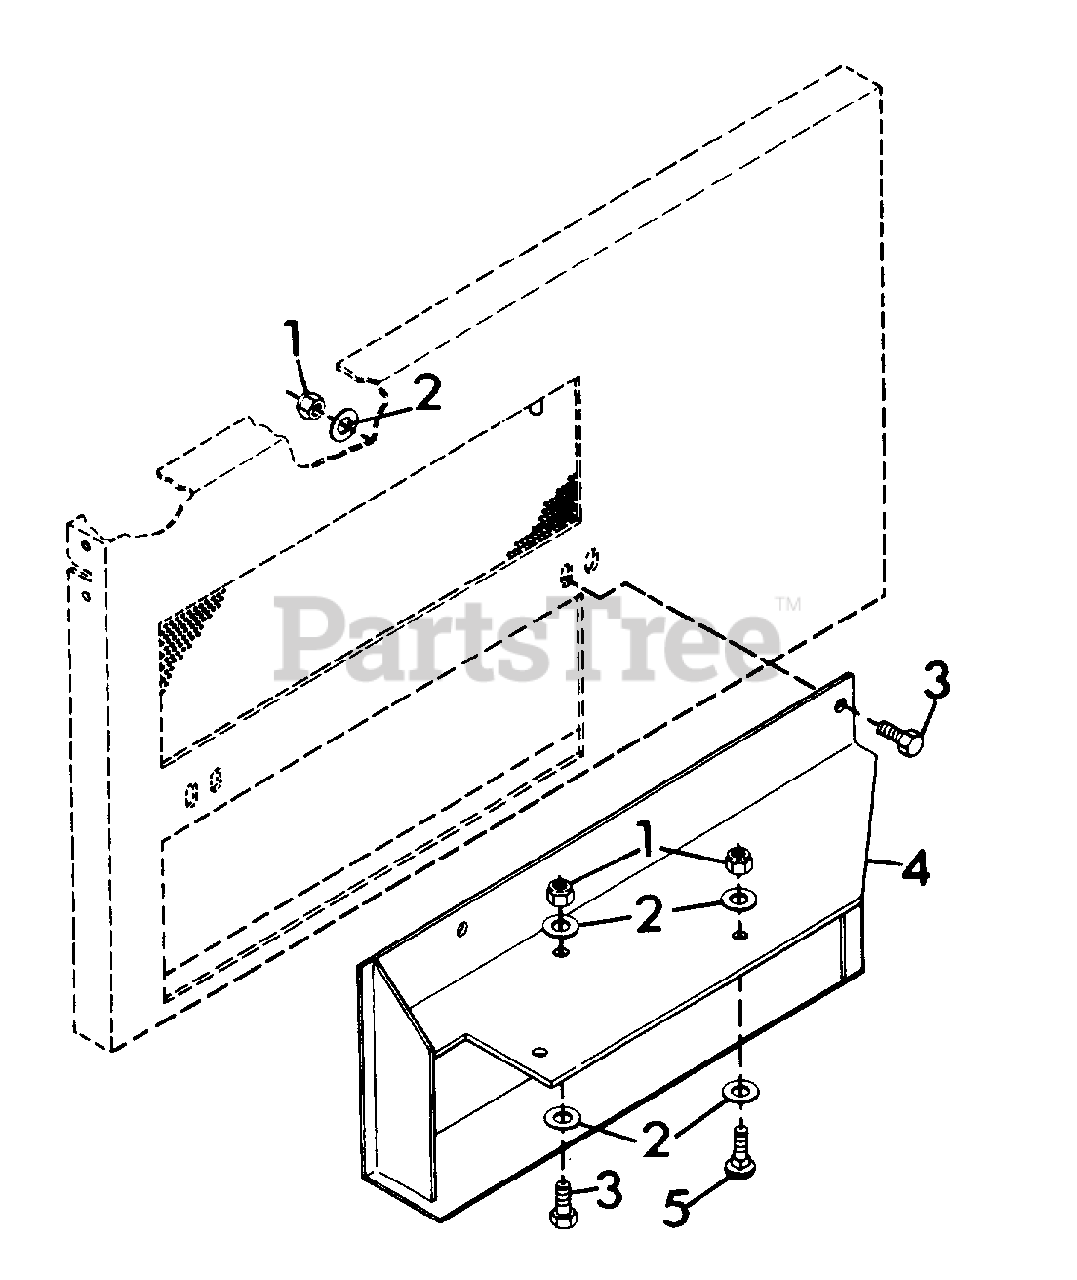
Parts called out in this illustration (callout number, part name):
1	NUT, LOCK 3/8-16
2	WASHER, FLAT .406X.812X.065
3	BOLT, HEX 3/8-16X1.00
4	WELDMENT, CHUTE ADAPTER
5	BOLT, 3/8-16X1.00 RD HD SQ NK
